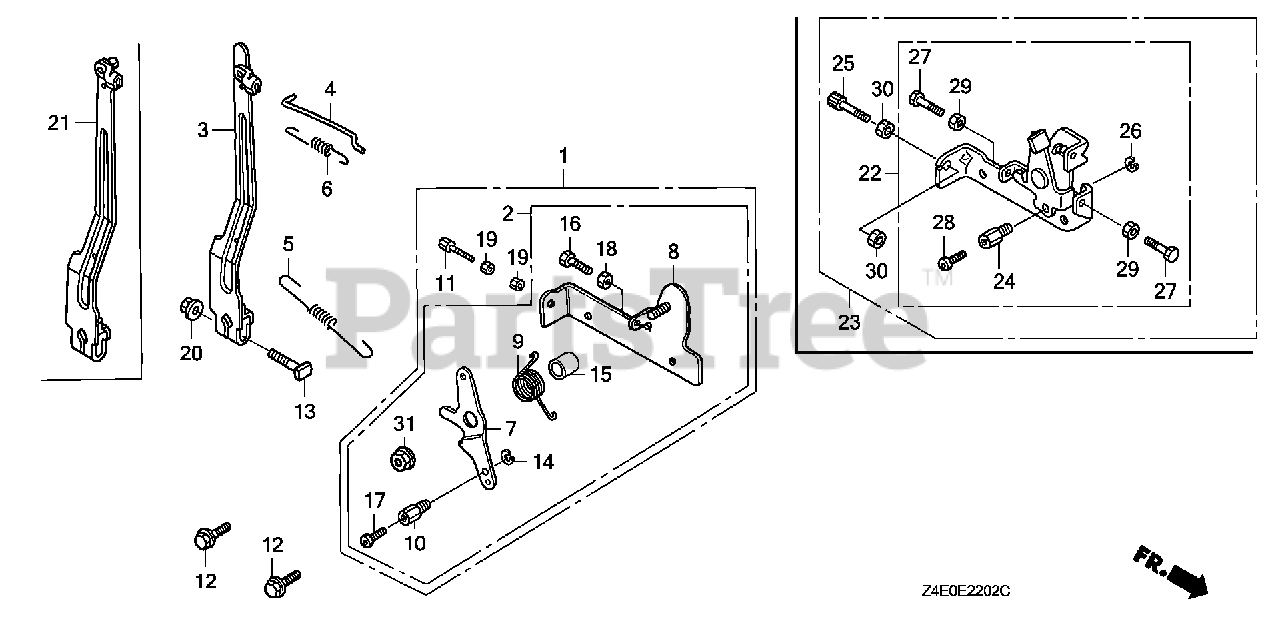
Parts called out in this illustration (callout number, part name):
1	CONTROL ASSY. (REMOTE)
3	ARM, GOVERNOR
4	ROD, GOVERNOR
5	SPRING, GOVERNOR
6	SPRING, THROTTLE RETURN
7	LEVER, CONTROL (REMOTE)
8	BASE, CONTROL (REMOTE)
9	SPRING, RETURN
10	HOLDER, WIRE
11	BOLT, CABLE ADJUSTING (6X34)
12	BOLT, FLANGE (6X14) (CT200)
13	BOLT, GOVERNOR ARM
14	CIRCLIP (5MM)
15	COLLAR, CONTROL LEVER
16	BOLT, HEX. (5X20)
17	SCREW, PAN (4X6)
18	NUT, HEX. (5MM)
19	NUT, HEX. (6MM)
20	NUT, FLANGE (6MM)
31	NUT, FLANGE (6MM)
